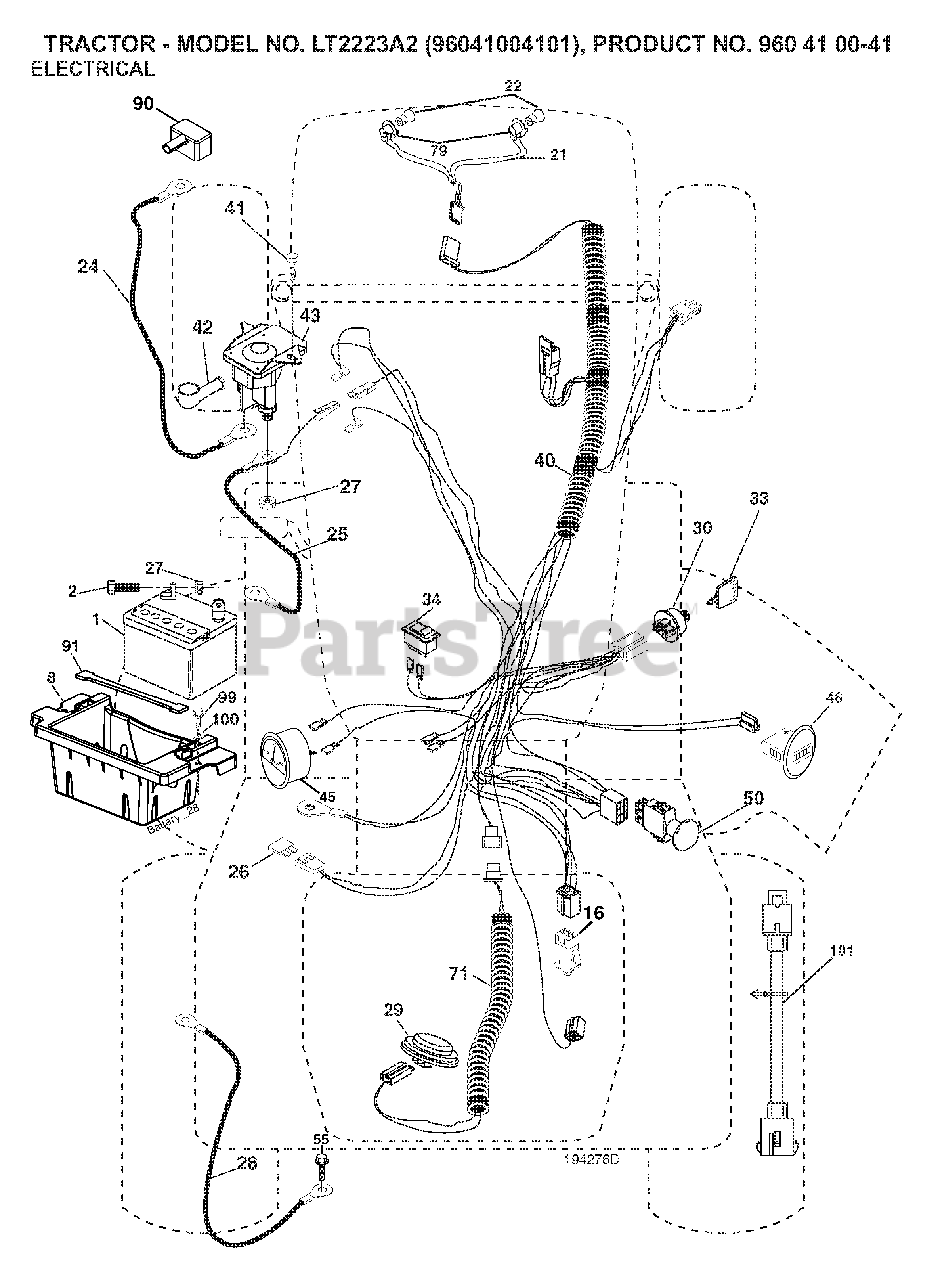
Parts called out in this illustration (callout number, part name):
1	BATTERY 12V .35 AMP
8	BOX.BATTERY.MOUNT.FRONT.LT
16	SWITCH INTERLOOK PUSH-IN
21	HARNESS.W/LIGHT SOCKET
22	LIGHTBULB
24	CABLE.BATT.POS.WIRE.TG.DA SOL
25	CABLE.START.RED.17.5".
26	FUSE 20AMP
27	NUT
28	CABLE GROUND 6 GA 21" 90T BLK
29	SWITCH.SEAT.DELTA.OPC.
30	SWITCH.IGN.DELTA.W.LGH.ROS
33	KEY MLD GEN DELTA
34	SWITCH LT
40	HARNESS IGN. DASH
41	SCREW
42	TERMINAL COVER
43	SOLENOID.W/BRASS.PLUNG
46	HOURMETER SNAP-IN
50	PTO SWITCH
55	SCREW 5/16"
71	HARNESS-CHASSIS SUB
79	BULB HOLDER ASM.
90	COVER.TERMINAL.BATTERY
91	STRAP, BATTERY MOUNT
99	SCREW HEXWSHR 1/4-20X3/4
101	PIGTAIL.MATNLK.NEW.HAR
